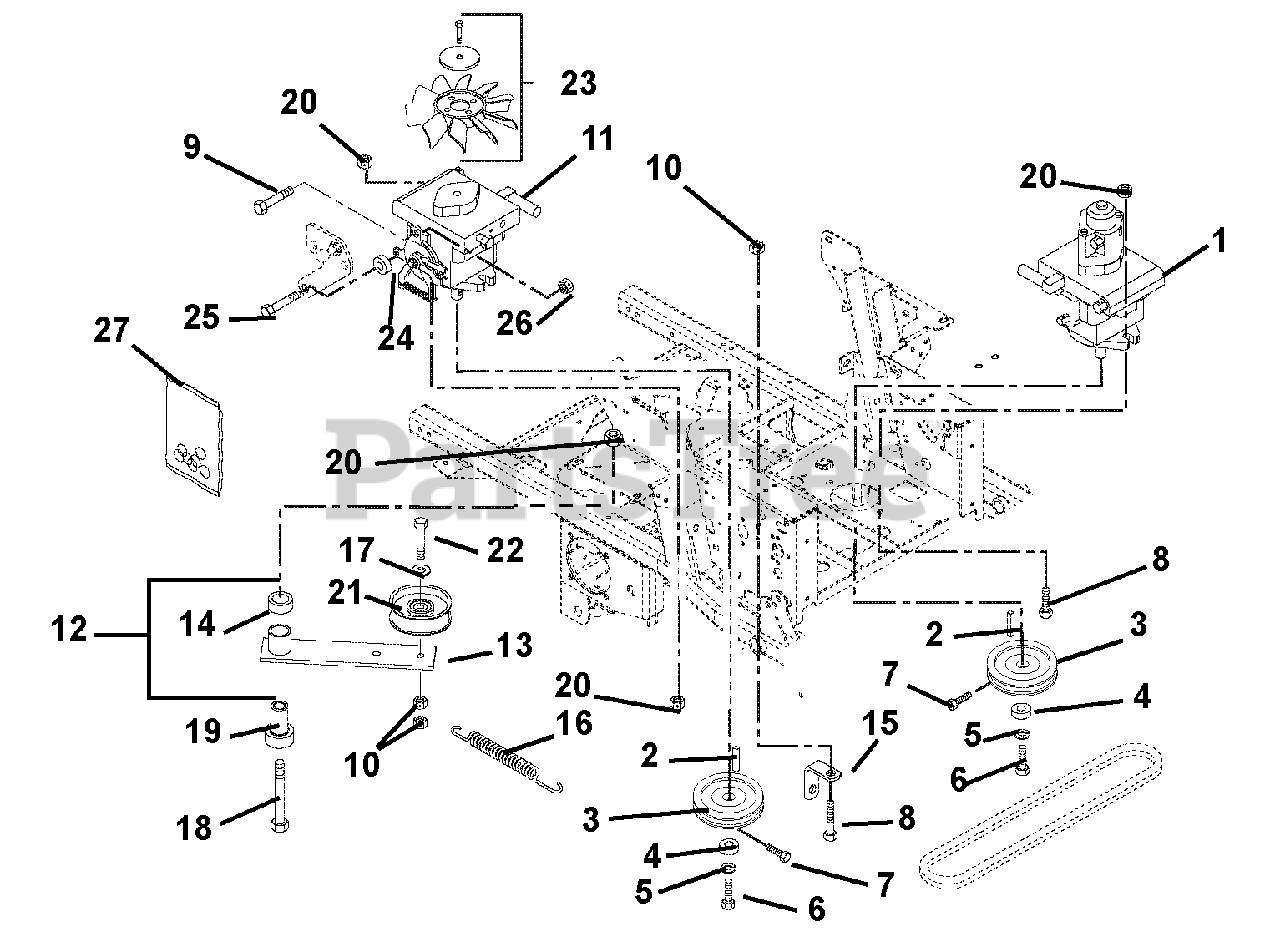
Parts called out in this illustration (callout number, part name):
1	Pump, Hydraulic with Auxiliary (992149, 150, 153, 154, 157, 159)
2	Key, Square 5 x 5 x 30mm Plain
3	Sheave. Poly V .671 x 4.125
4	Washer, Flat Steel .281 x 1.000 x .063
5	Washer, Locking .25 x .062
6	Bolt, Hex M6 x 1.0 x 16
7	Screw, Socket Head 1/4-20 x 1/2
8	Bolt, Hex .50-13 x 1.50 Grade 5
9	Bolt, Hex .31-18 x .75 Grade 5
10	Nut-Locking-Top-Flange .38-16
11	Pump, Hydraulic BDP-21 with Thru Fan
12	Assembly, Idler Arm Guard Drive (Includes 13 & 14)
13	Weldment, Idler Arm Ground Drive
14	Bushing, 1.00 x 1.125 x 1.936
15	Anchor, Spring Idler
16	Spring, Tension .120 x .845 x 6.500
17	Washer, Flat Steel .39 x .75 x.125
18	Bolt, Hex .50-13 x 3.50 Grade 5
19	Bearing, Pedestal
20	Nut, Locking Top Flange .50-13
21	Assembly, 4" Idler (.75 Wide)
22	Bolt, Hex .38-16 x 2.25 Grade 5
23	Fan, Hydro Pump Cooling
24	Spacer .318 x .43 x .375
25	Bolt, Hex .31-18 x 1.25 Grade 5
26	Nut, Locking Top Flange .31-18
27	Kit, Pump Seal (BDP-21A)(One kit required for each pump)
